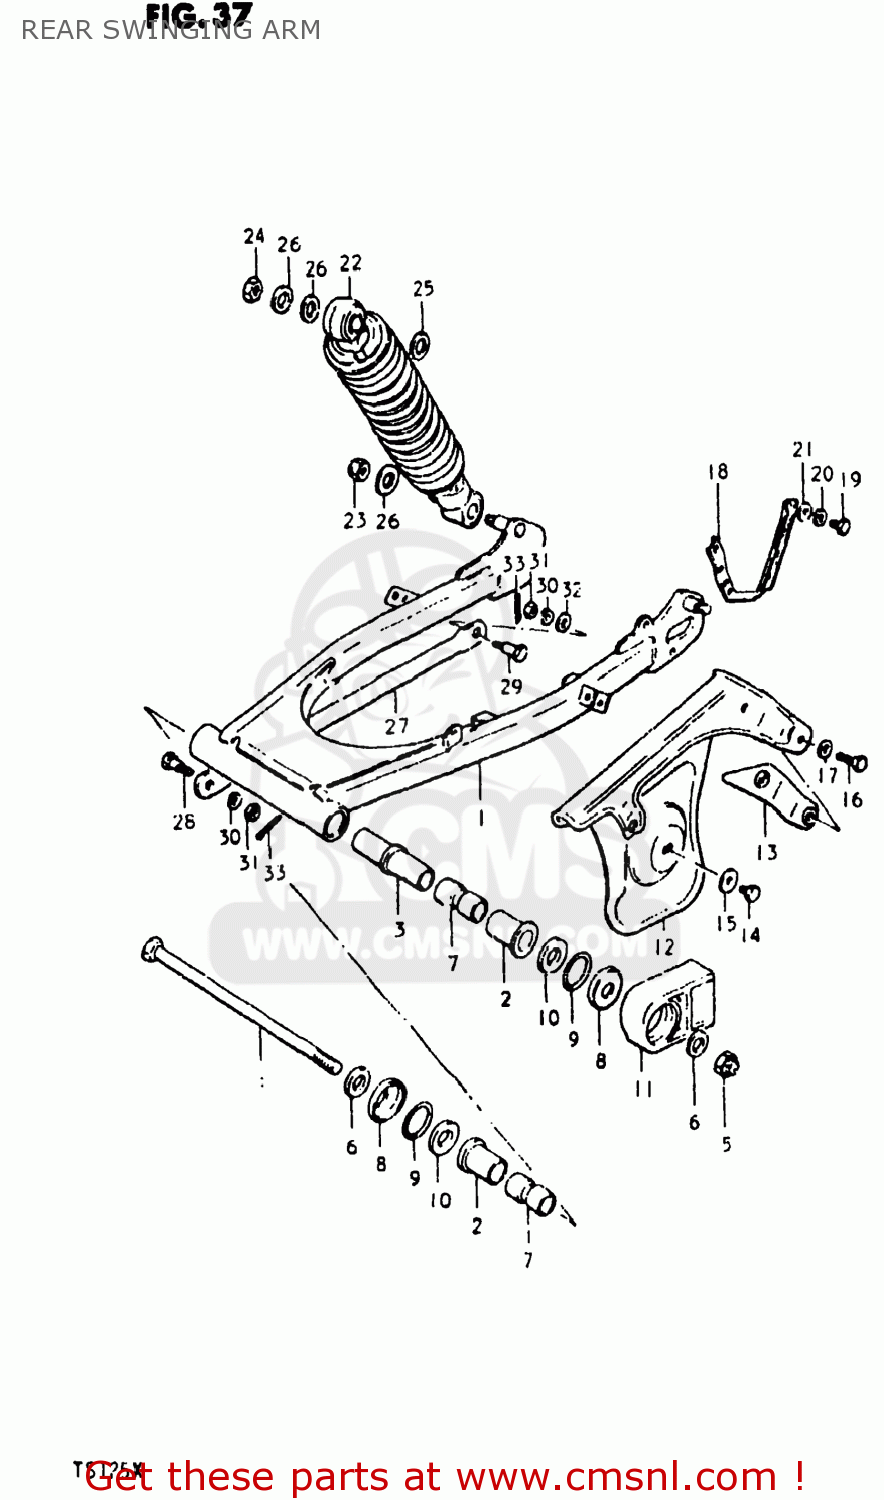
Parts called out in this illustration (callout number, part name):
1	SWING ARM ASSEMBLY,REAR
2	BUSH
3	SPACER,RR SWGARM PIVOT CTR
4	SHAFT,REAR SWING ARM
5	NUT 12MM
6	WASHER
7	SPACER,RR SWGARM PIVOT
8	COVER,SWGARM BUSH DUST SEAL
9	O RING(D:2,ID:24.5)
10	WASHER(12.5X24X2.3)
11	BUFFER,CHAIN TOUCH DEFENSE
12	CASE,CHAIN
13	REINFORCEMENT,CHAIN CASE
14	BOLT(6X8)
15	WASHER
16	BOLT, UPPER
17	WASHER
18	GUIDE,CHAIN
19	BOLT 8X12
20	LOCK WASHER
21	WASHER
22	ABSORBER ASSEMBLY,REAR SHOCK
23	NUT, LOWER LH
24	NUT
25	WASHER
26	WASHER
27	TORQUE LINK,REAR
28	BOLT(8X22)
29	BOLT(8X26.5)
30	LOCK WASHER
31	NUT
32	WASHER
33	PIN
